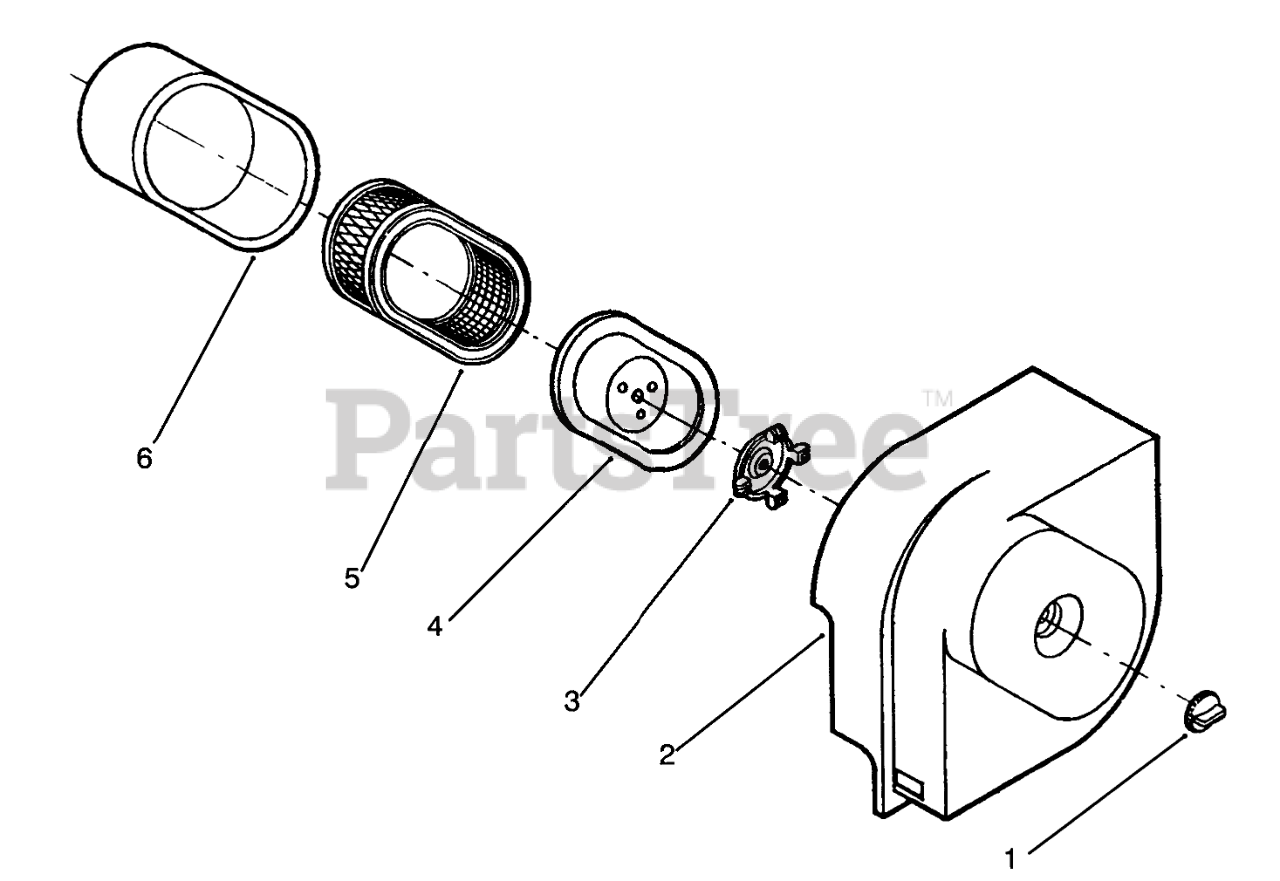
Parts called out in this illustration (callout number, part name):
1	KNOB-TOOL LESS
2	AIR CLEANER COVER
3	INNER COVER KNOB
4	ELEMENT COVER
5	AIR CLEANER ELEMENT
6	FLTR ELEMENT WRAPPER
